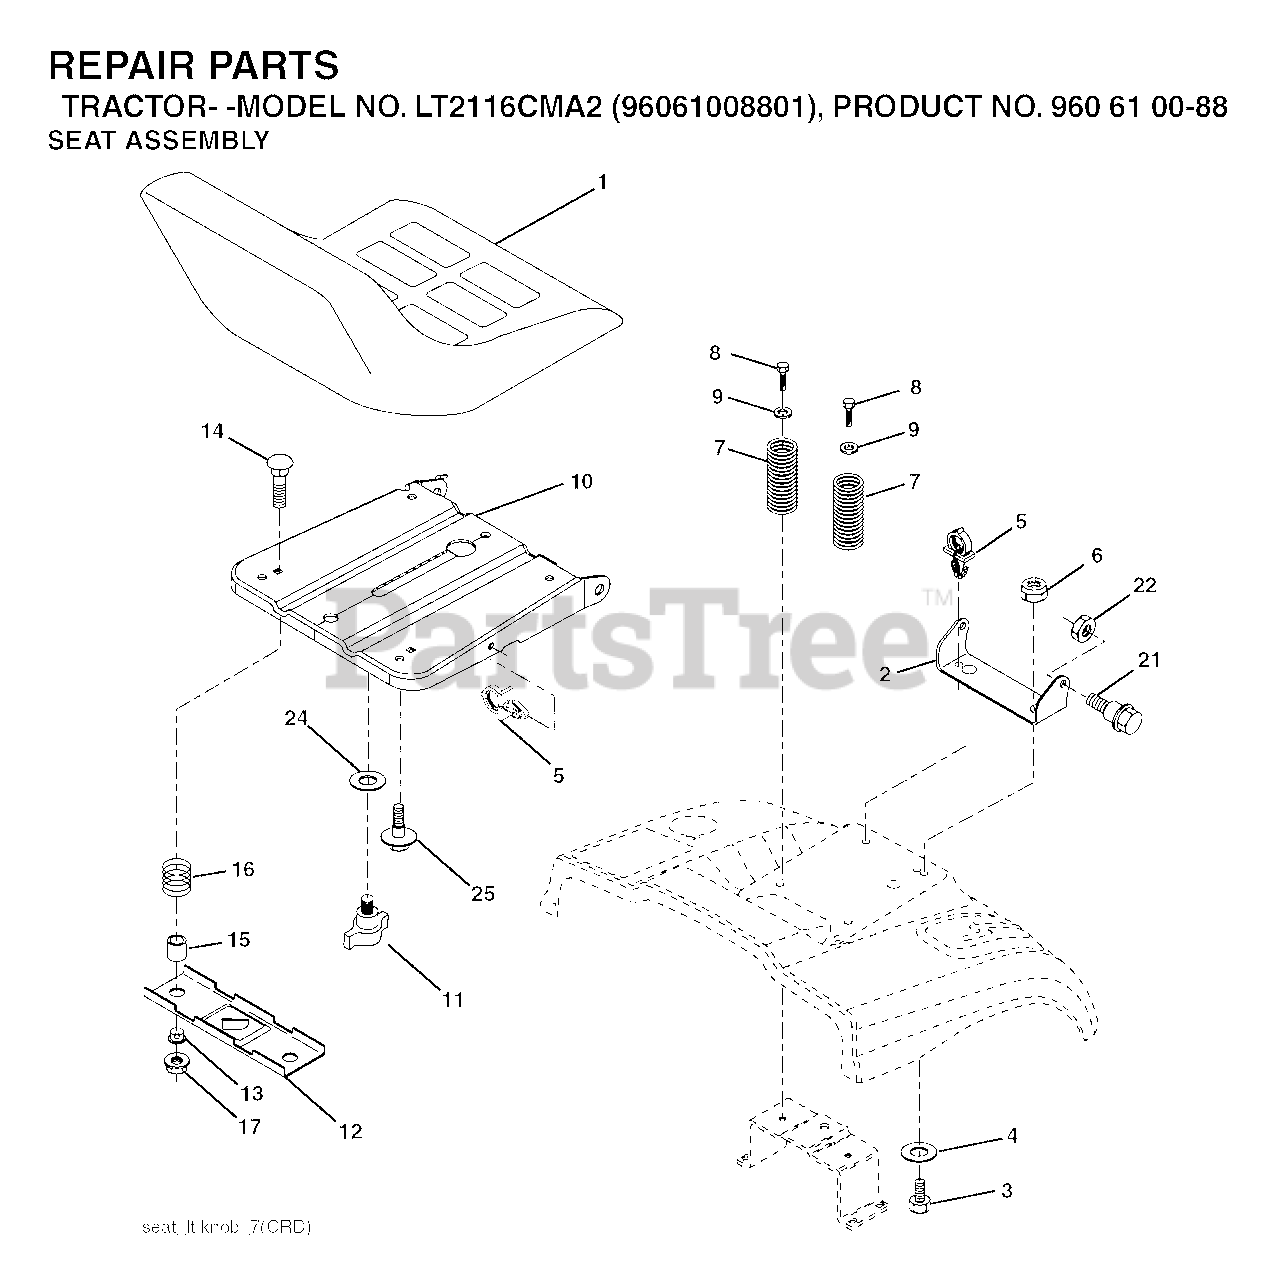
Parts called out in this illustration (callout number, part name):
1	SEAT.XG150.BLK.KB/SLD.NO-LOGO
2	SEAT PIVOT BRKT
4	WASHER PM
5	PUSH CLIP
6	NUT
7	SPRING COMPRESSION
8	SCREW 3/8-16X1
9	WASHER
10	PAN.ASM.SEAT.1SLOT
11	KNOB.SEAT.ADJ.WINGNUT
12	BRKT.MNTNG.SWITCH.SEAT
14	BOLT.ROUND.HEAD.SQUARE.NECK
15	SPACER SPLIT
16	SPRING COMPRESSED
17	NUT T
21	BOLT.SHOULDER.5/16-18
22	NUT.71038.31-18.HEX.NYLOCK
25	BOLT,SHOULD
